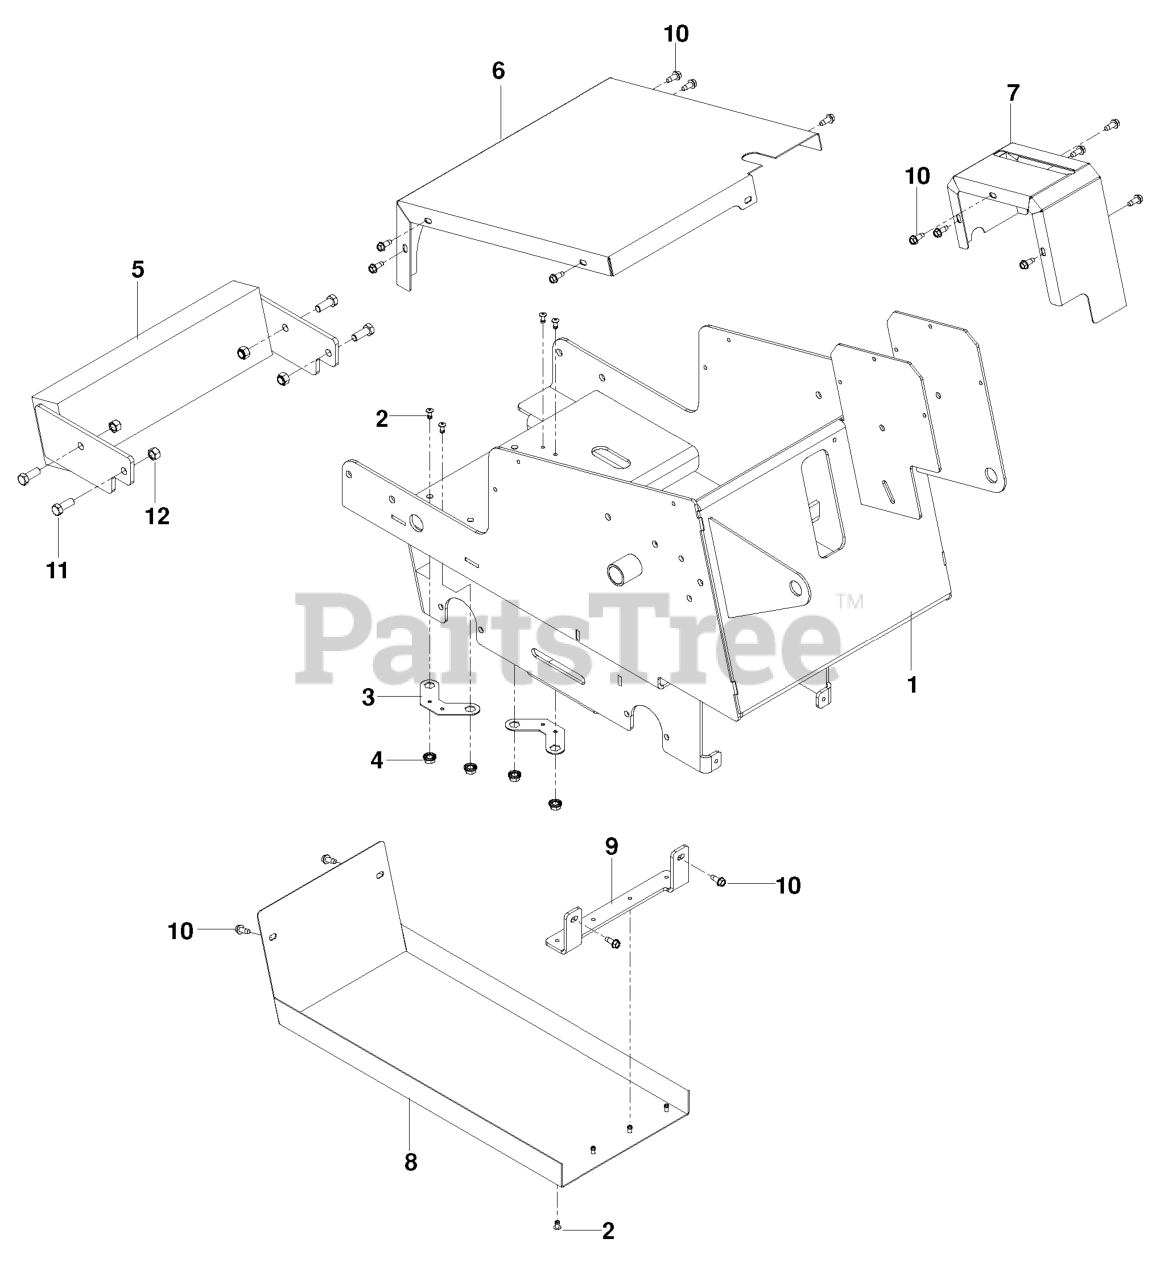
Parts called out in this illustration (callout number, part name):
1	CHASSIS - ORANGE
2	RIVERT, 3/16, STAVEX
3	NUT PLATE, BLACK
4	5/16-18 NYLOC FLANGE NUT
5	WLDMT - WEIGHT, BLACK
6	COVER - TOP, ORANGE
7	COVER - SHIFT, ORANGE
8	BELLY PAN, ORANGE
9	END BRACKET, ORANGE
10	SCREW 1/4 X 5/8
11	HCS 3/8-16X1.GRD.5.ZD
12	NUT 3/8-16 NYLOC
